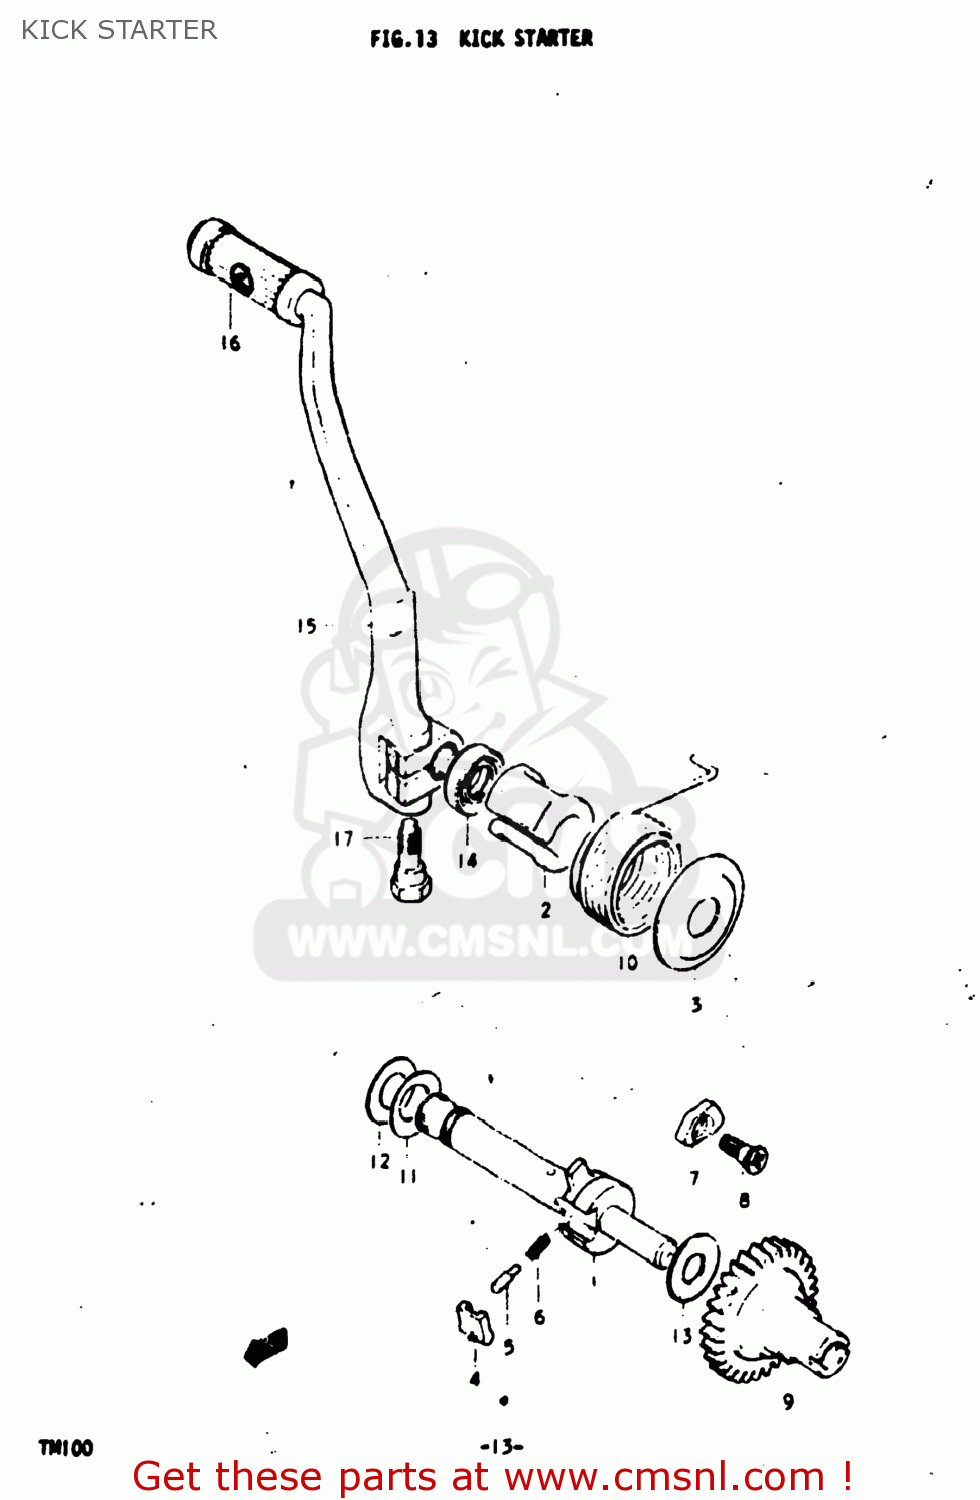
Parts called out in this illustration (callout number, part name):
1	SHAFT,KICK STARTER
2	GUIDE,KICK STARTER SFT SPRING
3	HOLDER,KICK STARTER SHAFT SPR
4	PAWL,KICK STARTER
5	PIN(5X15.5)
6	SPRING
7	LIFTER,KICK STARTER PAWL
8	SCREW(6X19)
9	GEAR,KICK STARTER DRIVE
10	SPRING
11	WASHER(16X30X0.5)
12	WASHER
13	WASHER
14	SEAL,OIL(16X30X8)
15	LEVER ASSEMBLY,KICK STARTER
16	RUBBER,KICK STARTER PEDAL
17	BOLT
